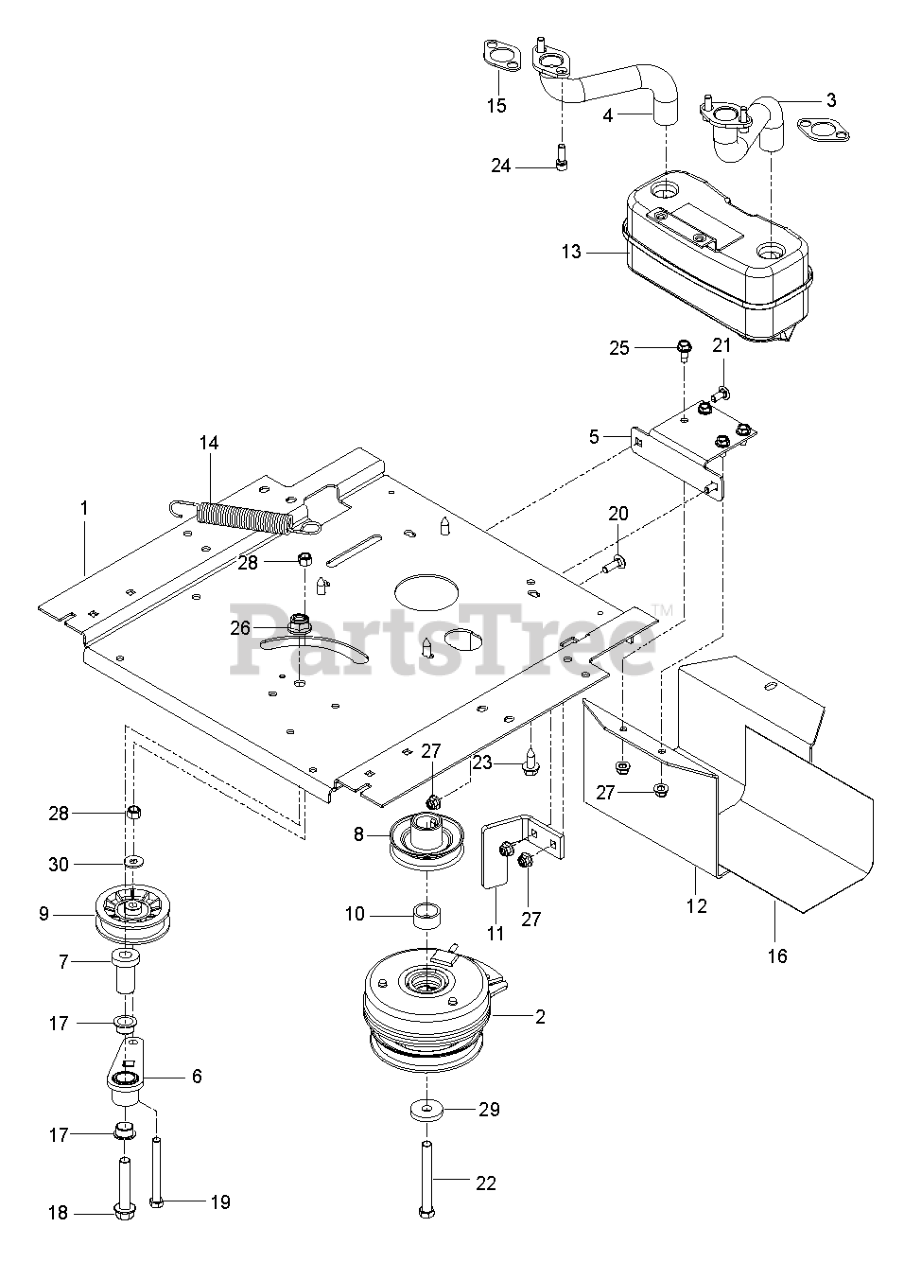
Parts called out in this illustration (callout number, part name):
1	PLATE.ENGINE.PNT.23"FRAME.EDIP
2	CLUTCH.105.FT-LBS
3	EXHAUST.TUBE.LH.BS/TWIN
4	EXHAUST.TUBE.RH.B&S.TWIN.INTEK
5	BRACKET MUFFLER MS431BLK
6	ARM IDLER
7	SPINDLE.IDLER
8	PULLEY.ENGINE
9	PULLEY, IDLER
10	T & B SPACER
11	STOP, CLUTCH, BLACK
12	GUARD.MUFFLER.WO.TOW.HITCHX431
13	MUFFLER ASM TWIN
14	SPRING, DECK DRIVE
15	GASKET.MUFFLER
16	HEAT SHIELD
17	BEARING.FLANGED.PLASTIC.3/4ID
18	BOLT.FLANGE.1/2-13 X 2.75.GRD5
19	HCS 3/8-16X3-1/2 TAPBLT GR5 ZD
20	RHSNB 5/16C X 1
21	Bolt, Carriage 5/16-18 x 3/4 Gr. 5
22	CLUTCH BOLT7/16-20X3.5 GR524HR
23	SCREW 3/8-16X1
24	SCREW.SOCKET.HEAD.5/16-18
25	Screw, Hex Washer Head, Threaded, Rolling 5/16-18 x 3/4 Type TT
26	NUT, 1/2-13 HEX FLG NYLOC ZD
27	5/16-18 NYLOC FLANGE NUT
28	NUT 3/8-16 NYLOC
29	Washer 1 - 1/2 OD x 15/32 ID x .250 (AYP part number)
30	WASHER 5/16 FLAT
